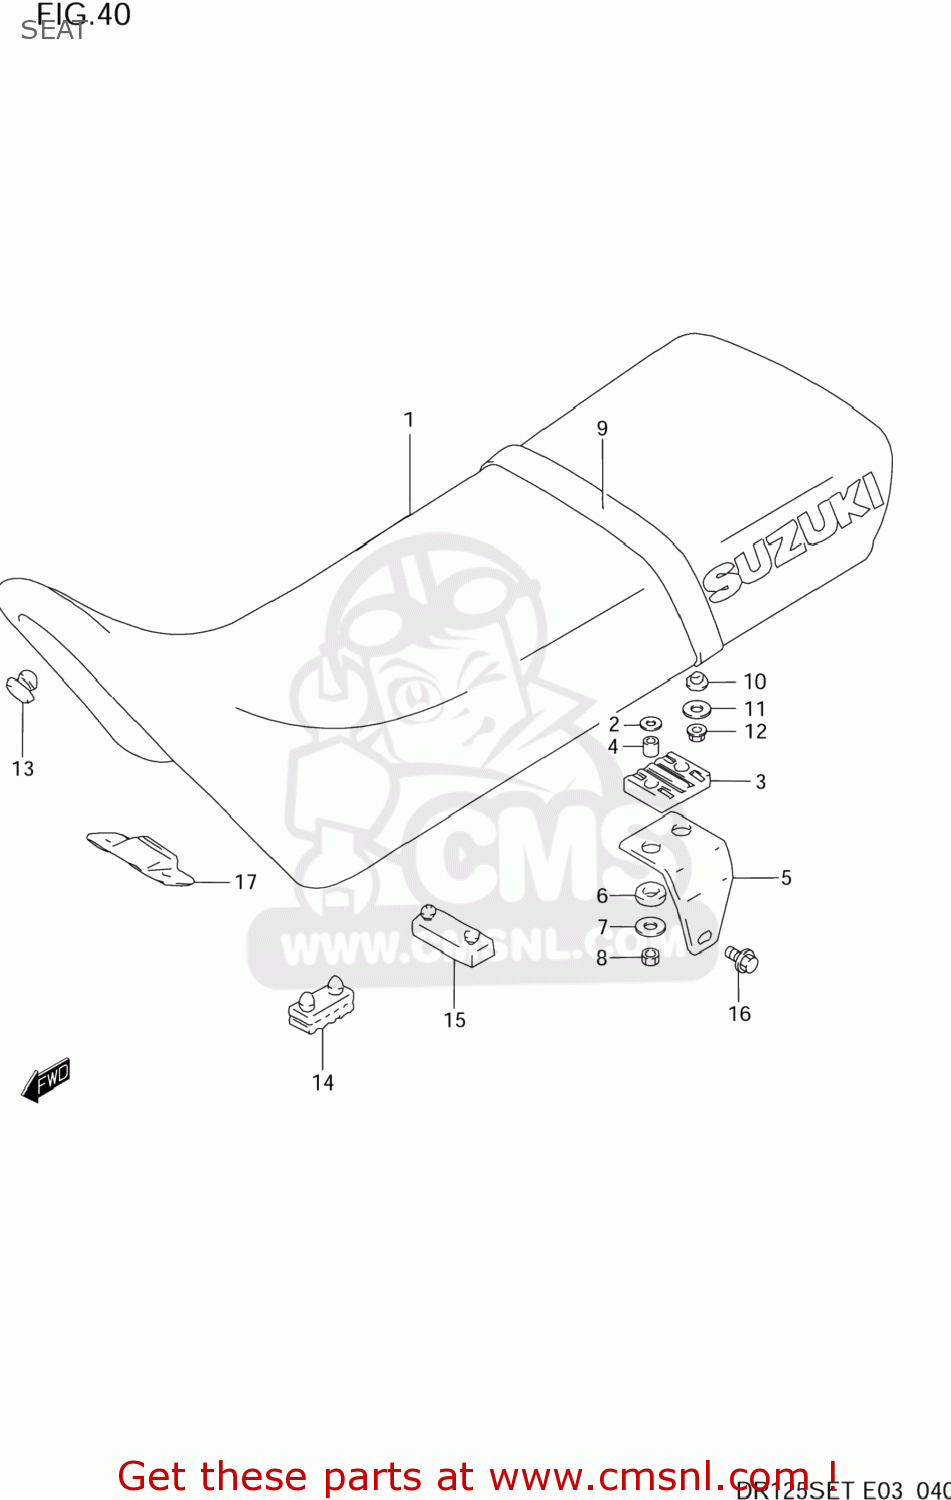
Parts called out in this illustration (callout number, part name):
1	SEAT SET
2	WASHER
3	CUSHION,FR PLATE
4	SPACER,SEAT BRACKET
5	BRACKET,SEAT
6	CUSHION,SEAT FR
7	WASHER
8	NUT
9	BAND,SEAT
10	WASHER
11	WASHER
12	NUT
13	CUSHION
14	CUSHION,SEAT(40X20X15)
15	CUSHION,SEAT
16	BOLT
17	PLATE,SEAT FR HOOK
